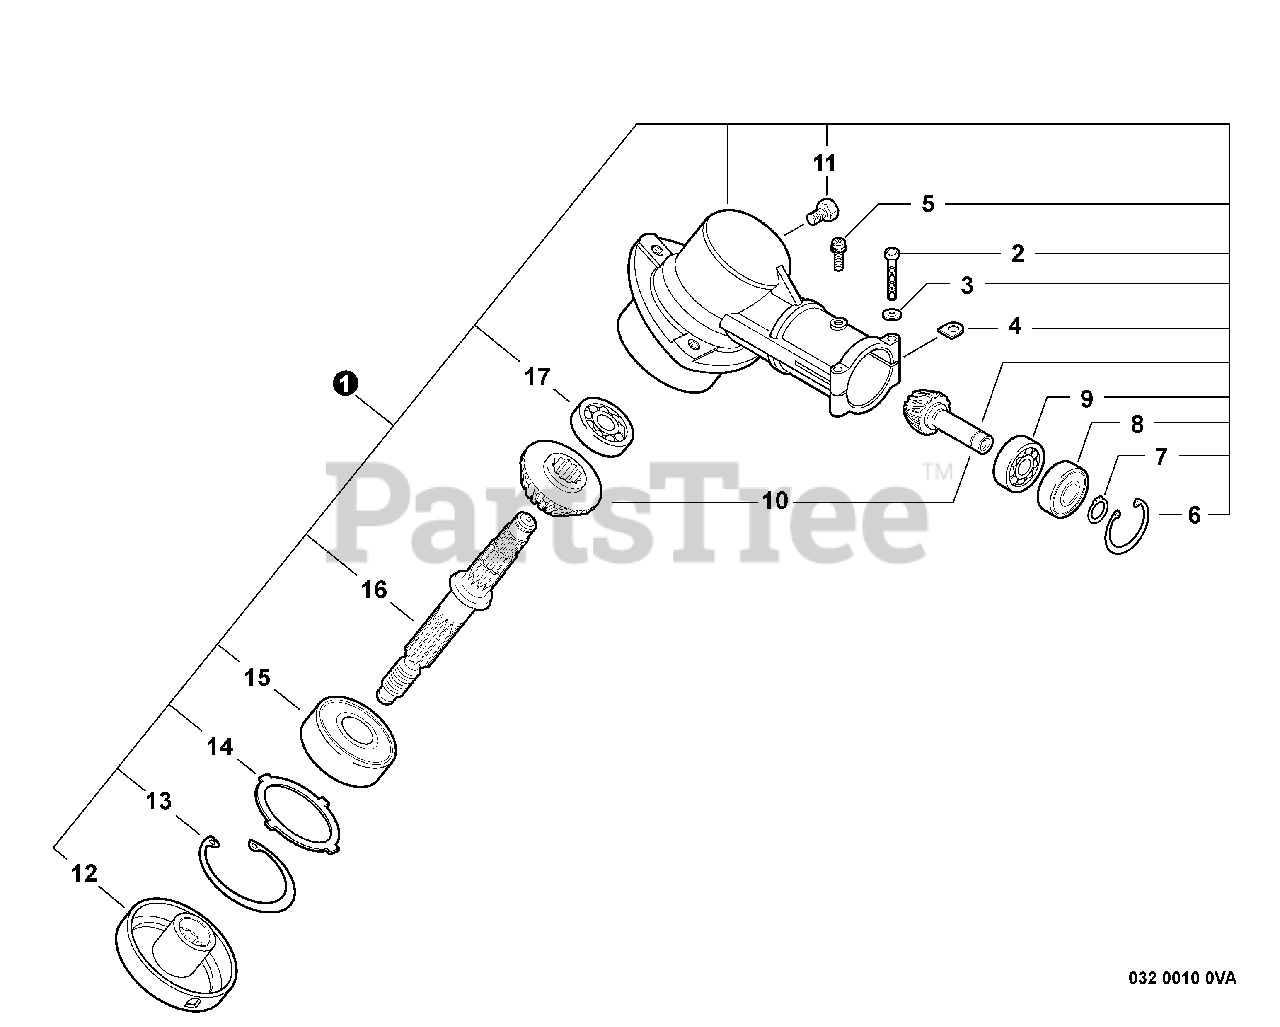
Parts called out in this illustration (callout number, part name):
1	GEAR CASE ASSY
2	BOLT - 5X35
3	WASHER - 5
5	SCREW - 5X10
6	RING, RETAINING - 22
7	RING, RETAINING - 10
8	BEARING, BALL - 6900Z
9	BEARING, BALL - 6900
10	GEAR SET - BEVEL
11	BOLT - 8X8
12	ADAPTOR, BLADE - UPPER
13	RING, RETAINING - 32
15	BEARING, BALL - 6201
16	GEAR - SHAFT
17	BEARING, BALL - 609
